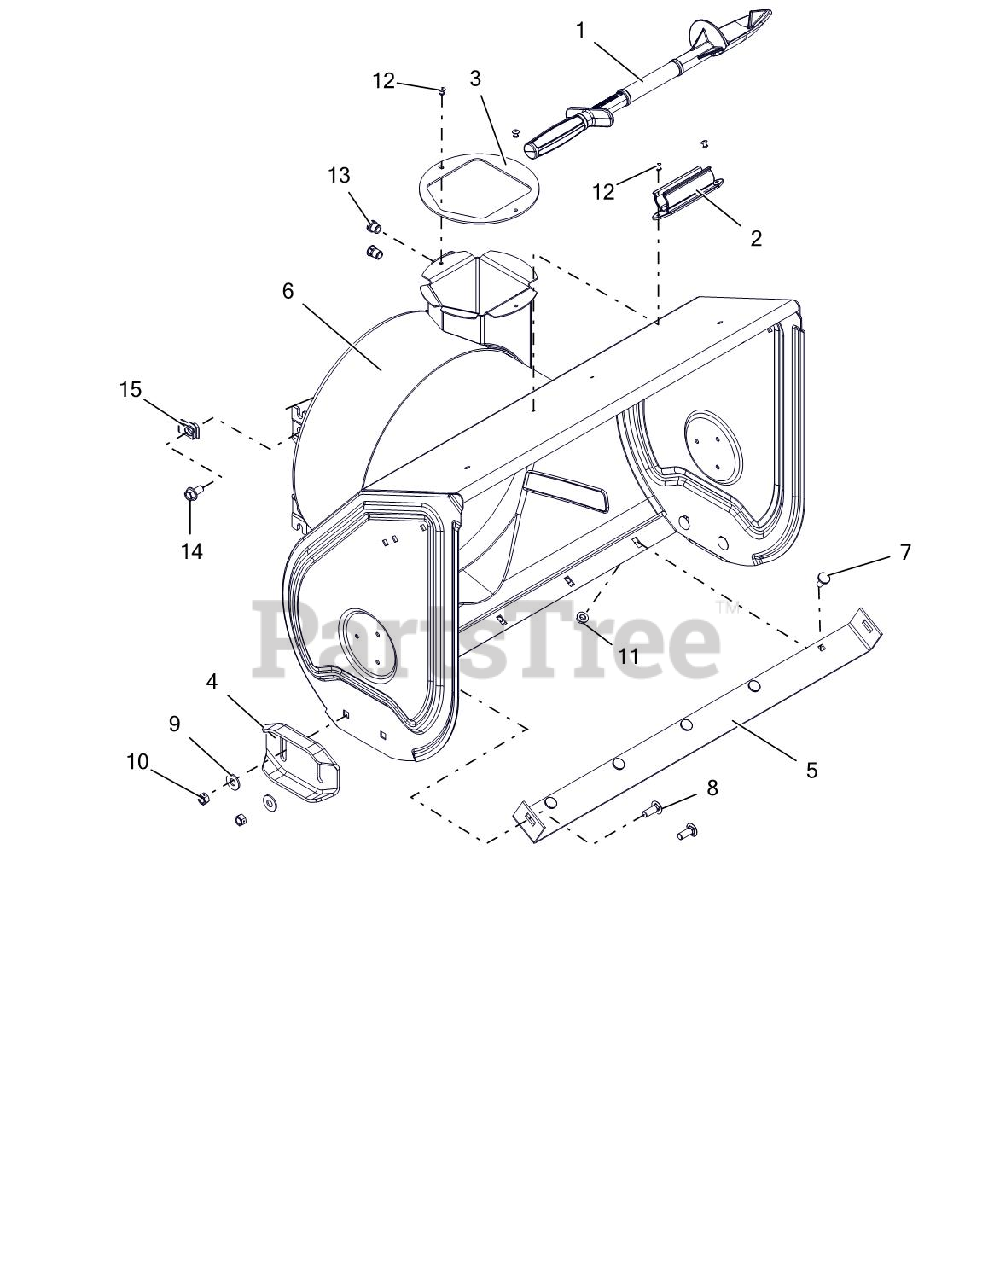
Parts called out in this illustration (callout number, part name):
1	DEVICE, SNOW CLEAN OUT
2	MOUNT, SNOW CLEAN OUT
3	BAFFLE, DISCHARGE NECK
4	SKID SHOE, REVERSIBLE - ORANGE
5	BLADE, SCRAPER - 28"
6	BLOWER HOUSING W/DECAL 28"
7	BOLT, MODIFIED HEAD CARRIAGE
8	@BLT-RDHDSHSQNK.38-16X1.0 G5YZ
9	@WSHR-FL-STL.438X1.00X.083 YWZ
10	@NUT-LK-CTR .38-16 YWZC
11	@NUT-LK-TOP-FLG .31-18 YWZC
12	RVT-POP .187 YZ
13	NUT, THREADED INSERT .38-16
14	BLT-SERHFWH .38-16X.75 YWZC
15	NUT-RTNR .375-16X.37
